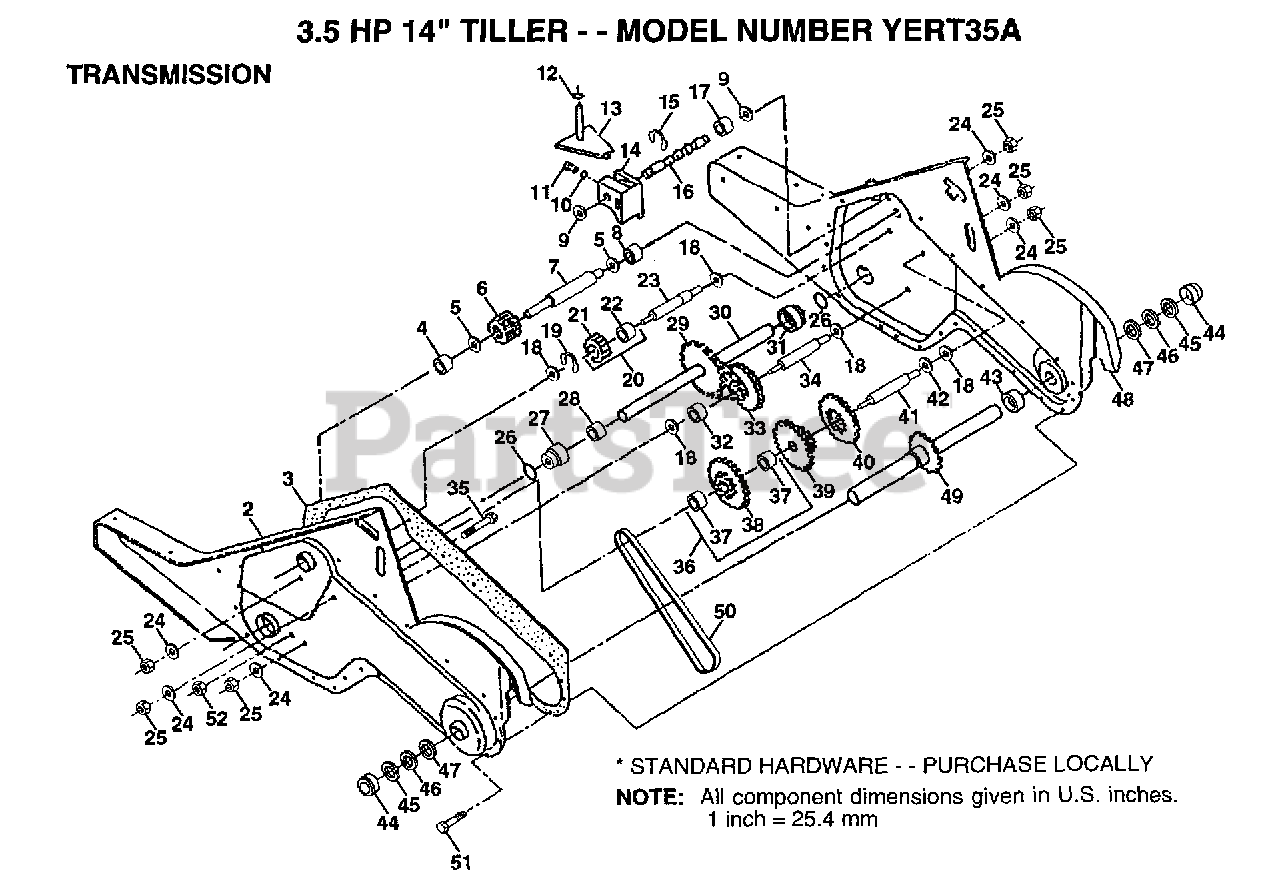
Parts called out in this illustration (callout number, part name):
3	GASKET TI
4	NEEDLE BRNG LT
5	"T, BEARING"
6	PINION-INPUT CRT
7	SHAFT-INPUT CRT
8	"TI, BEARING"
9	WASHER SEAL CRT
11	SPRING-SHIFT CRT
12	O-RING TI
13	ARM ASSY CRT
14	SHIFT FORK TI
15	KLIP RING
16	SHAFT SHIFT CRT
17	SPACER SPLIT CRT
18	WASHER
19	KLIP RING
20	GEAR ASSY CRT
21	GEAR-REV IDLR CRT
22	NEEDLE BEARING TI
23	SHAFT CRT
24	LOCKWASHER
25	NUT.ASF.HEX.7/16
26	O RING CRT
27	"CRT, BEARING"
28	BUSHING TI
29	CHAIN CRT
32	SPACER TI
33	SPRCKT 8 GEAR CRT
34	SHFT 2ND RED. CRT
35	SCRW WHIZ LOK CRT
36	SPROCKET ASM.
37	BEARING
39	GEAR TI
40	GEAR TI
41	REDUCTION SHFT TI
42	BRNG RACE
43	SPACER TI
44	CUP.FORMED.
45	RING SPIRAL CRT
49	TINE SHAFT
50	CHAIN.50 LINK TI
51	SCREW CRT
52	NUT.HEX.5/16-18
